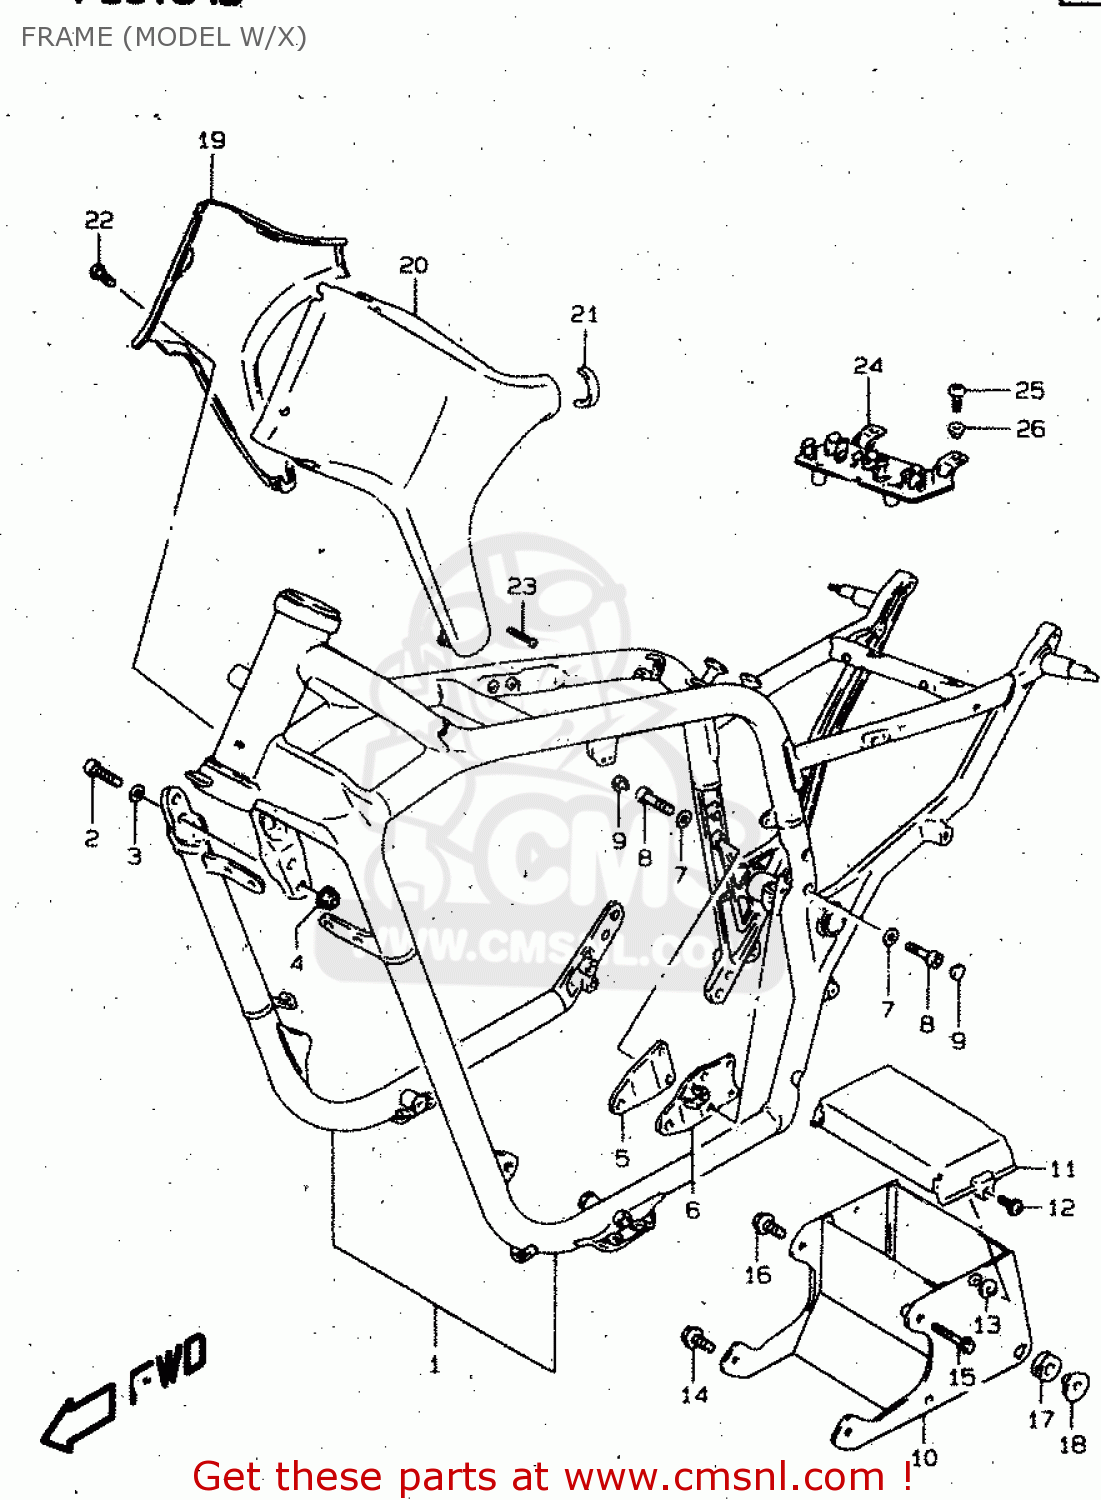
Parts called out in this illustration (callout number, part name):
1	FRAME SET
2	BOLT(10X33)
3	WASHER
4	NUT 10MM
5	PLATE,ENG MTG NO.4,R
6	PLATE,MOUNT NO.4,L
7	WASHER
8	BOLT(8X32)
9	CAP(OD:14.5)
10	HOLDER,BATTERY
11	COVER,BATTERY
12	SCREW(5X12)
13	WASHER
14	BOLT
15	BOLT
16	BOLT(8X40)
17	CUSHION
18	BUSH
19	COVER COMP,FRAME HEAD
20	COVER,FRM.HD.,
21	PROTECTOR,FRAME HEAD COVER
22	SCREW 6X10
23	SCREW
24	HOLDER,COUPLER
25	SCREW
26	WASHER
